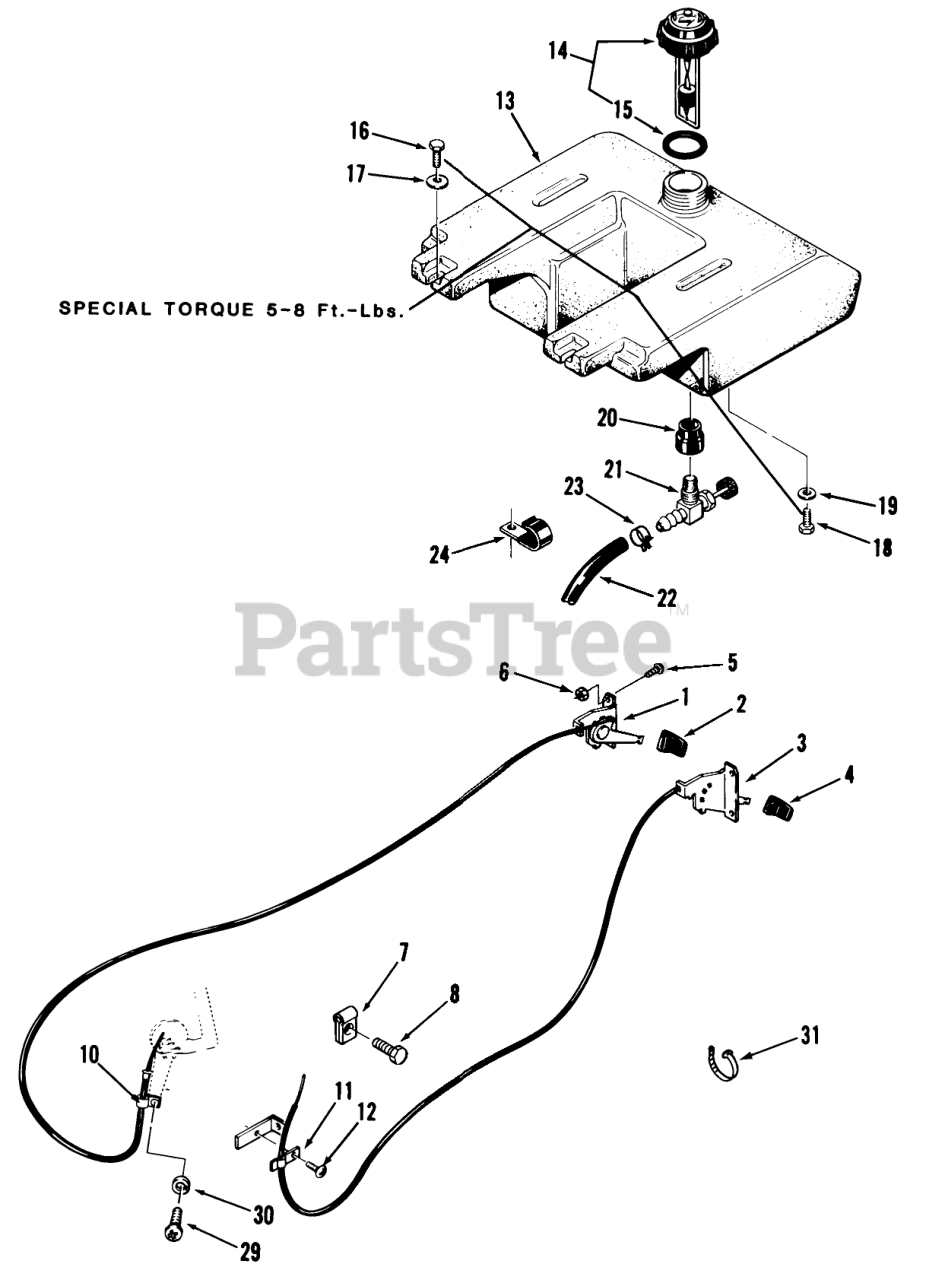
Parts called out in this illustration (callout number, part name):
1	CONTROL-THROTTLE
2	KNOB-THROTTLE
3	CONTROL-CHOKE
4	KNOB-CHOKE
5	Screw
6	Nut
7	THROTTLE CONTROL CLP
8	Screw
10	Clip
11	CLAMP-CABLE
12	SCREW
13	TANK-FUEL
14	ASSY-GAUGE CAP
15	GASKET-GAS CAP
16	Bolt
17	Washer
18	Bolt
19	Lockwasher
20	BUSHING
21	VALVE-FUEL
22	Fuel Line
23	Clamp
24	CLIP
24	CLAMP
29	Screw
30	Washer
31	Cable Tie
